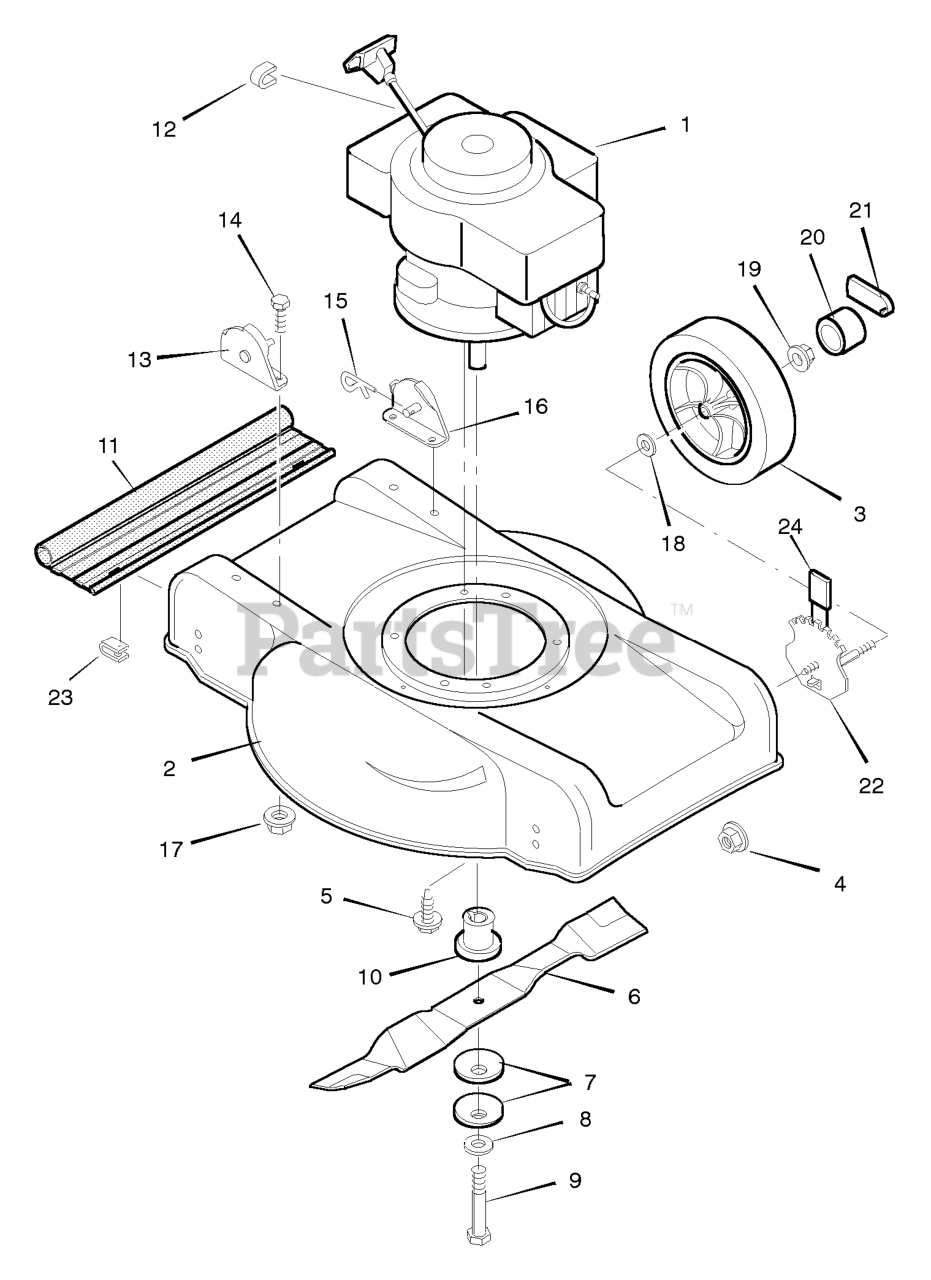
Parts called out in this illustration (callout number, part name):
1	Engine *
2	Housing, For Folding Handle
3	Wheel and Tire *
4	Locknut, Flange
5	Bolt, Engine
7	Washer, Belleville
9	Bolt, Hex
10	Adapter, Blade
11	Deflector, Rear
12	Stop, Rope
13	Bracket, Right Handle
15	Pin, Hair
16	Bracket, Left Handle
17	Nut
19	Locknut, Flange
20	Hub Cap
21	Hub Cap
22	Adjuster, Height
23	Retainer
